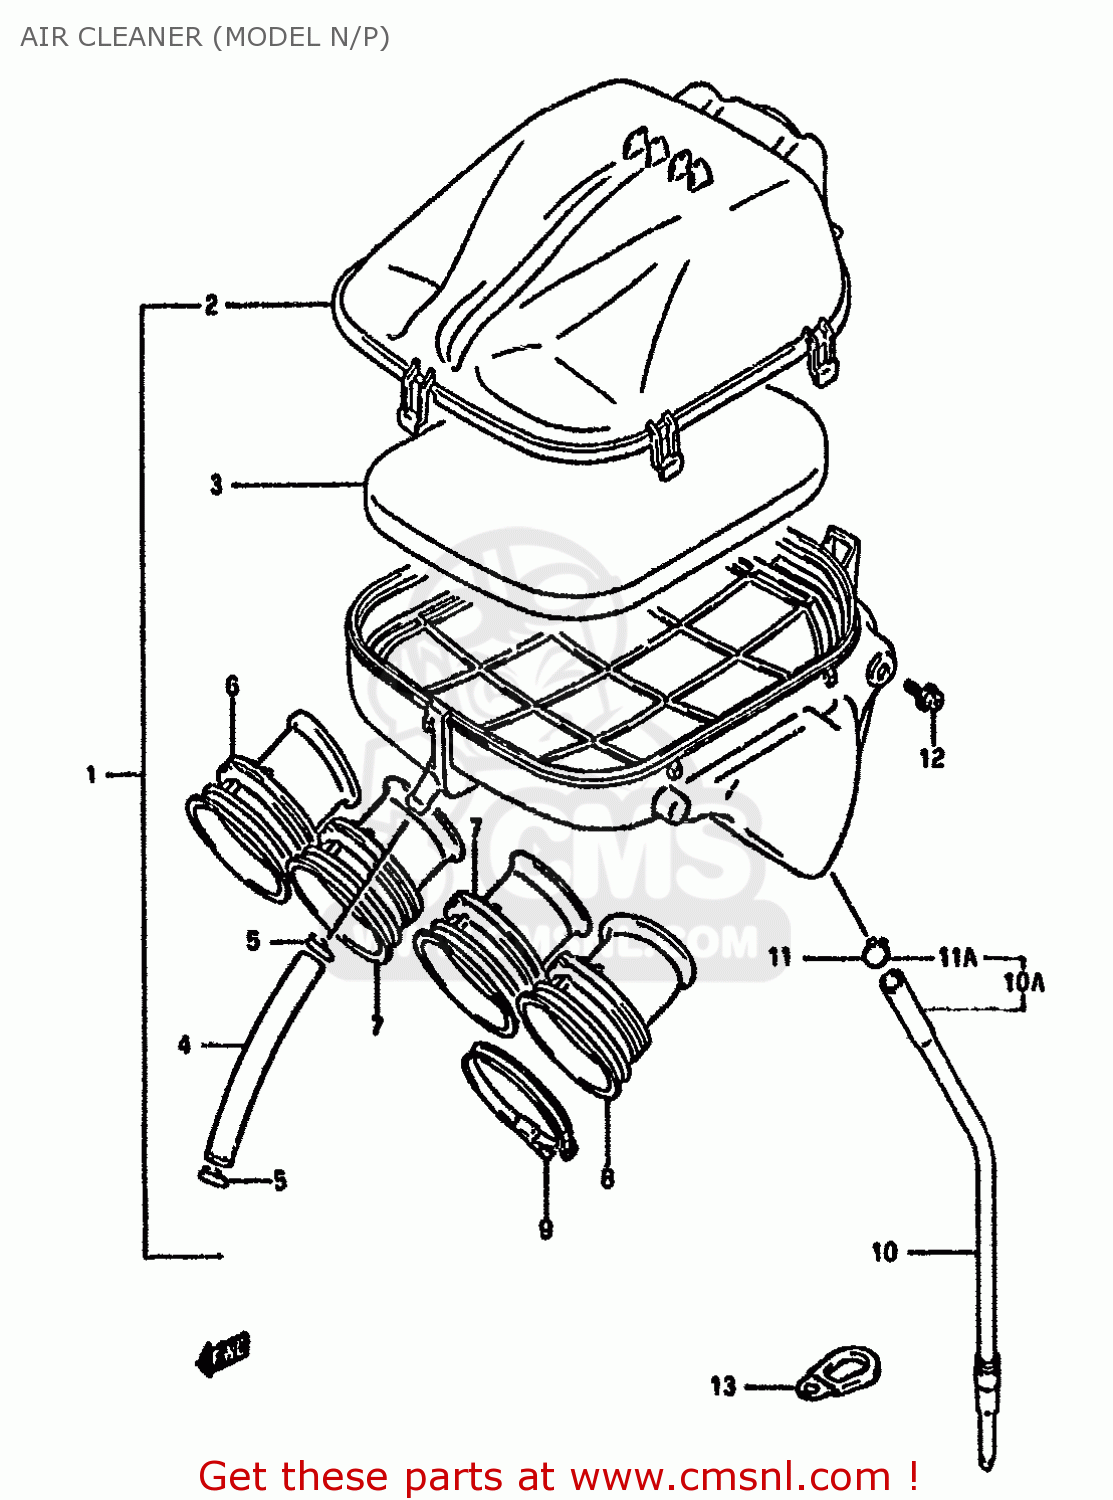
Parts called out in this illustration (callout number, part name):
1	CLEANER ASSY,AIR
2	CAP,AIR CLEANER
3	FILTER
4	TUBE,BREATHER
5	CLIP
6	TUBE,OUTLET NO.1
7	TUBE,OUTLET NO.2
8	TUBE,OUTLET NO.4
9	CLAMP
10	TUBE,DRAIN
10A	DRAIN TUBE
11	CLIP
11A	CLIP
12	SCREW
13	PLATE,DRAIN TUBE GUIDE
